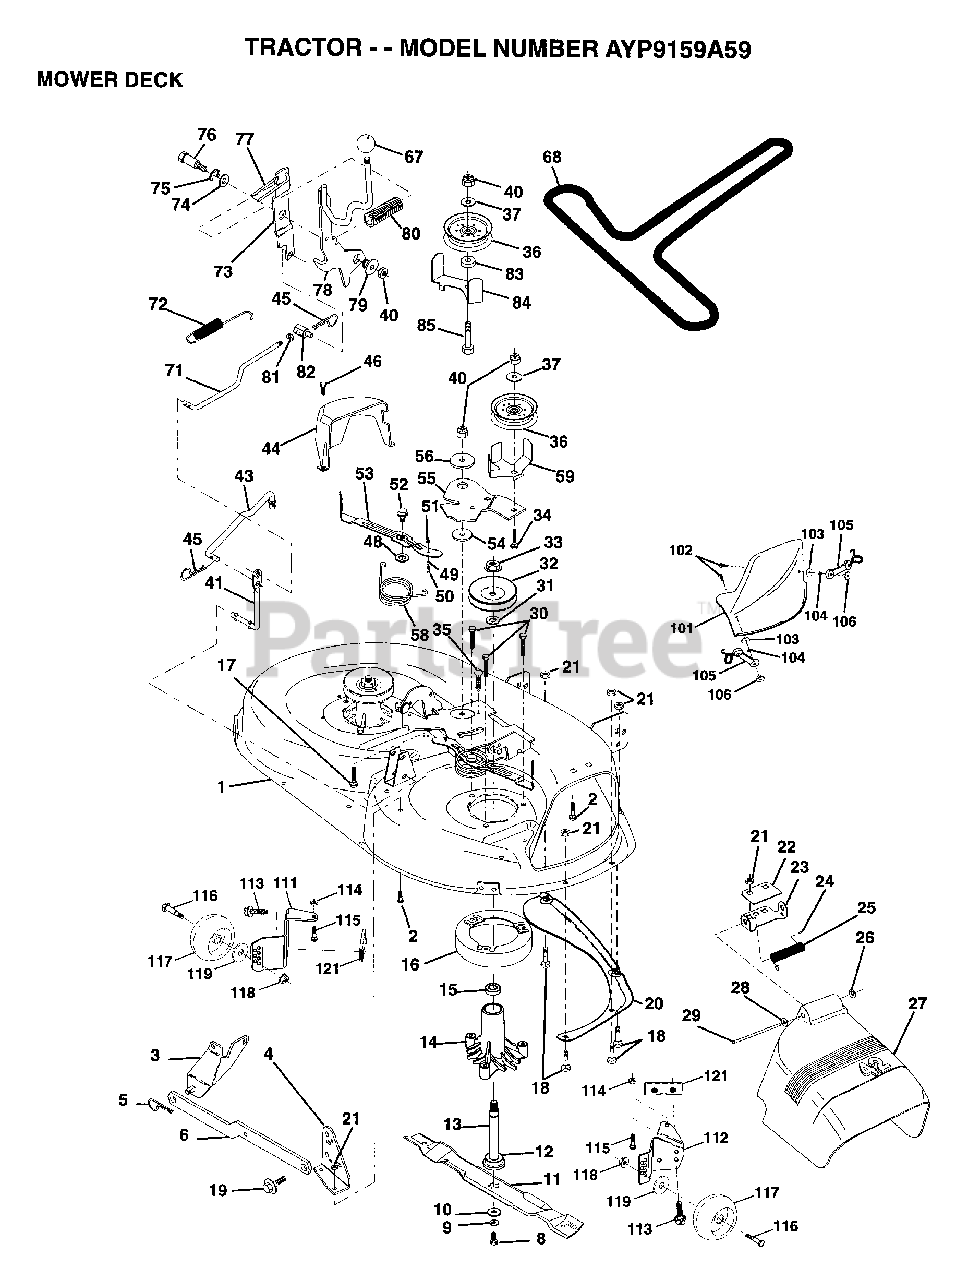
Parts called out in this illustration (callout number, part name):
1	DECK.WELD.42.
2	BOLT
3	BRKT ASM SWAY BAR
4	BRKT DECK SW BAR
8	BLADE BOLT
10	WASHER.HARD.BLADE
11	"BLADE.42"" MULCHER"
12	BEARING.BALL
14	HSG ASM MANDREL
15	BEARING
16	STRIPPER RND MWR
17	BOLT RDHD 3/8-16
18	BOLT
19	BOLT SHD 5/16-18
22	STIFFENER BRKT
23	DEFLECTOR BRKT
24	CAP-SLEEVE LT
25	SPRING TORSION
26	NUT PUSH M
27	DEFLECTOR.SHIELD
28	WASHER
29	HINGE ROD
31	WASHER
34	BOLT
35	XMAS TREE FASTNER
36	FLAT IDLER PULLEY
37	WASHER
41	PIVOT ROD
43	ROD CLUTCH W/NIBS
44	GUARD MAND LH BLK
45	RETAINER M
46	SCREW.1/4-20X5/8
48	HARD SMALL WASHER
50	SHOULDER BOLT
51	LOCKNUT
52	BOLT.SHLD.5/16-18
53	BRAKE PAD ARM ASM
54	HARDENED WASHER
56	SPACER RETAINER
58	SPRING TORSN BRAK
59	GUARD IDLER TUV
67	KNOB T (1/2-HOLE)
68	BELT.V.T-PATH
71	ROD CLUTCH 38/42
72	RETURN SPRING
73	CLUTCH ARM SECOND
74	WASHER
75	RING
76	SHOULDER BOLT
77	SPRING KEEPER
78	LEVER ASM CLT PRM
79	BUSHING
81	NUT
82	TRUNION ADJ
83	WASHER
85	BOLT
101	"COVER.MULCH.42"""
102	SCREW
103	WASHER #10
104	LOCKWASHER
106	WELDNUT
113	SCREW
116	BOLT.SHOULDER
117	WHEEL GAGE DONUT
118	LOCKNUT
119	WASHER
121	BRACKET.EXTRD.GWL
